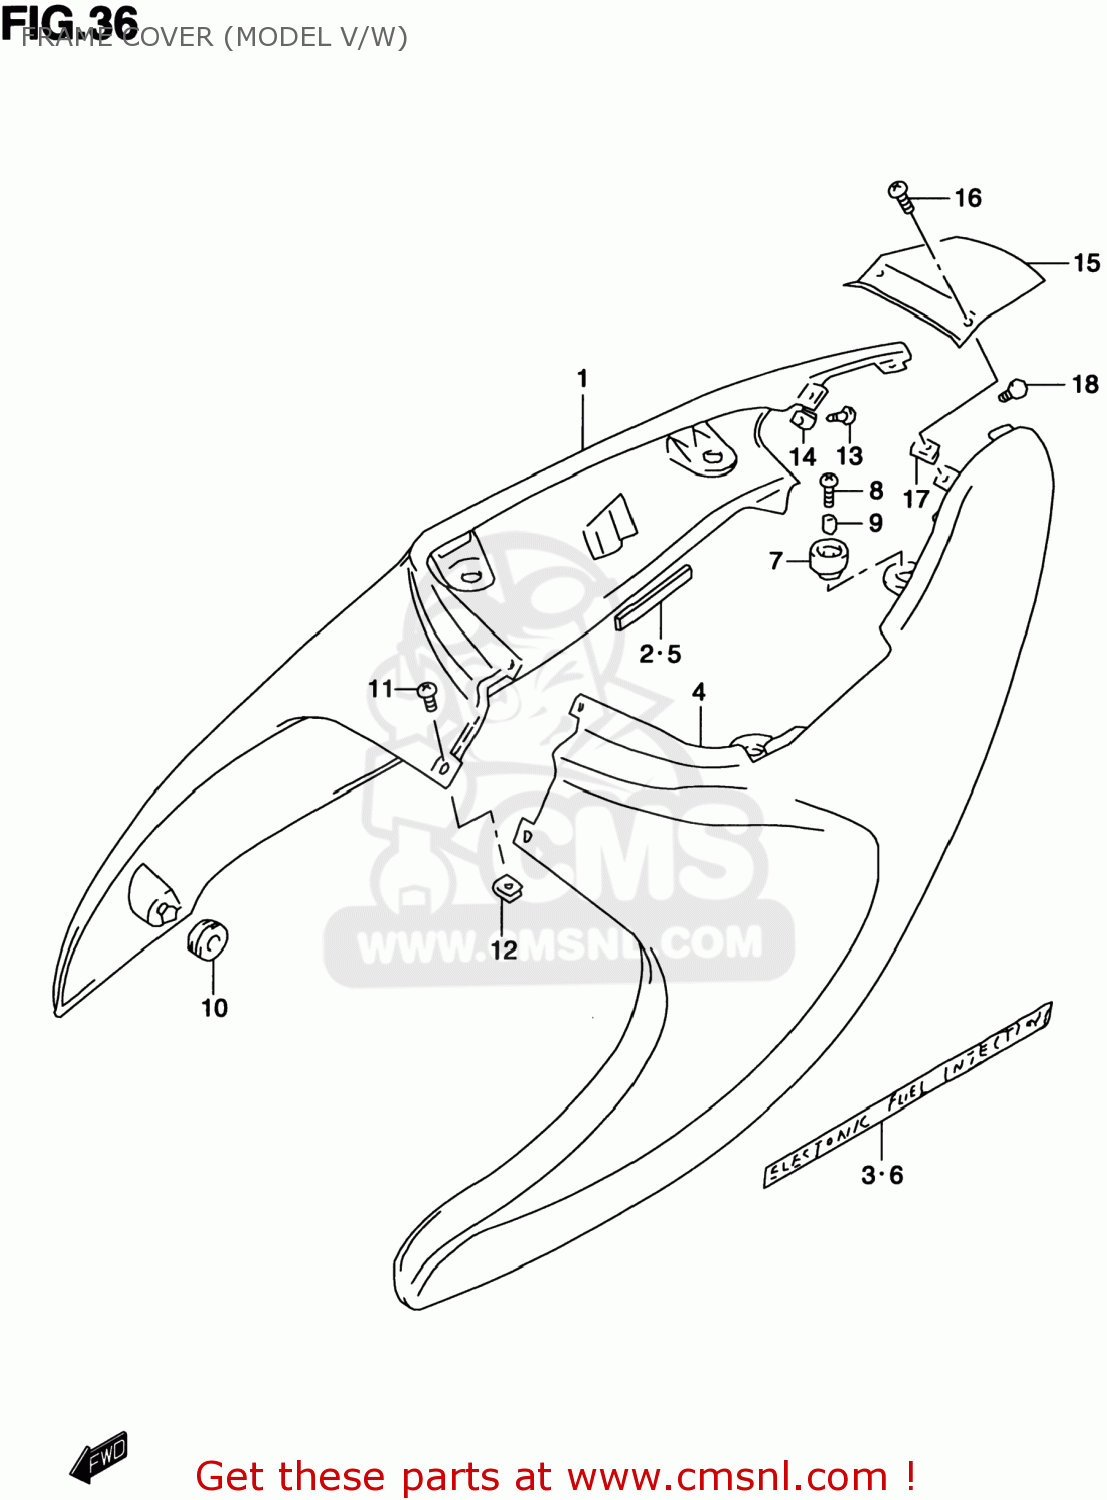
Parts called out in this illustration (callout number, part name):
1	COVER,FRAME,R(RED)
2	CUSHION,FRAME COVER
3	EMBLEM,FRAME COVER
4	COVER,FRAME,L(RED)
5	CUSHION,FRAME COVER
6	EMBLEM,FRAME COVER
7	CUSHION
8	SCREW(6X20)
9	SPACER(6.5X10X9.4)
10	CUSHION
11	SCREW
12	NUT
13	SCREW(5X16)
14	NUT
15	COVER,FRAME CTR
16	SCREW
17	NUT
18	CUSHION
